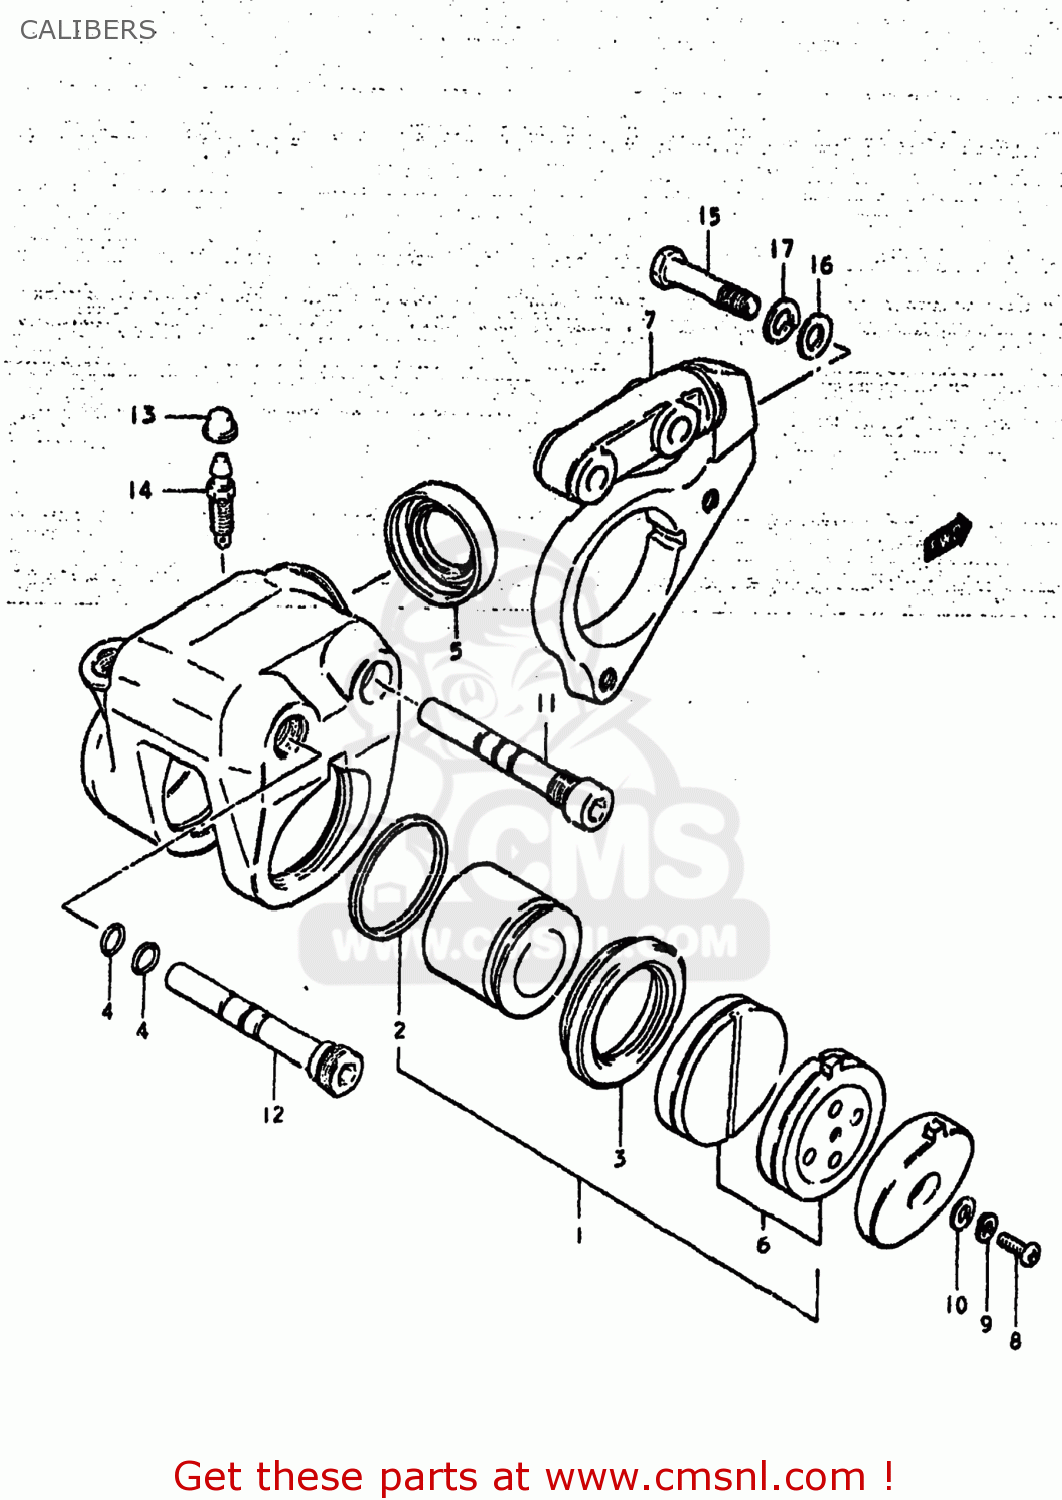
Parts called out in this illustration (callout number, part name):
2	SEAL,PISTON
3	BOOT,PISTON
4	O RING,AXLE CALIPER
5	BOOT,HOLDER
6	PAD SET (MCA)
7	HOLDER,CALIPER
8	SCREW
9	LOCK WASHER
10	WASHER
11	AXLE,CALIPER
12	AXLE NO.2
13	CAP,BLEEDER PL
14	BLEEDER
15	BOLT
16	WASHER
17	LOCK WASHER
